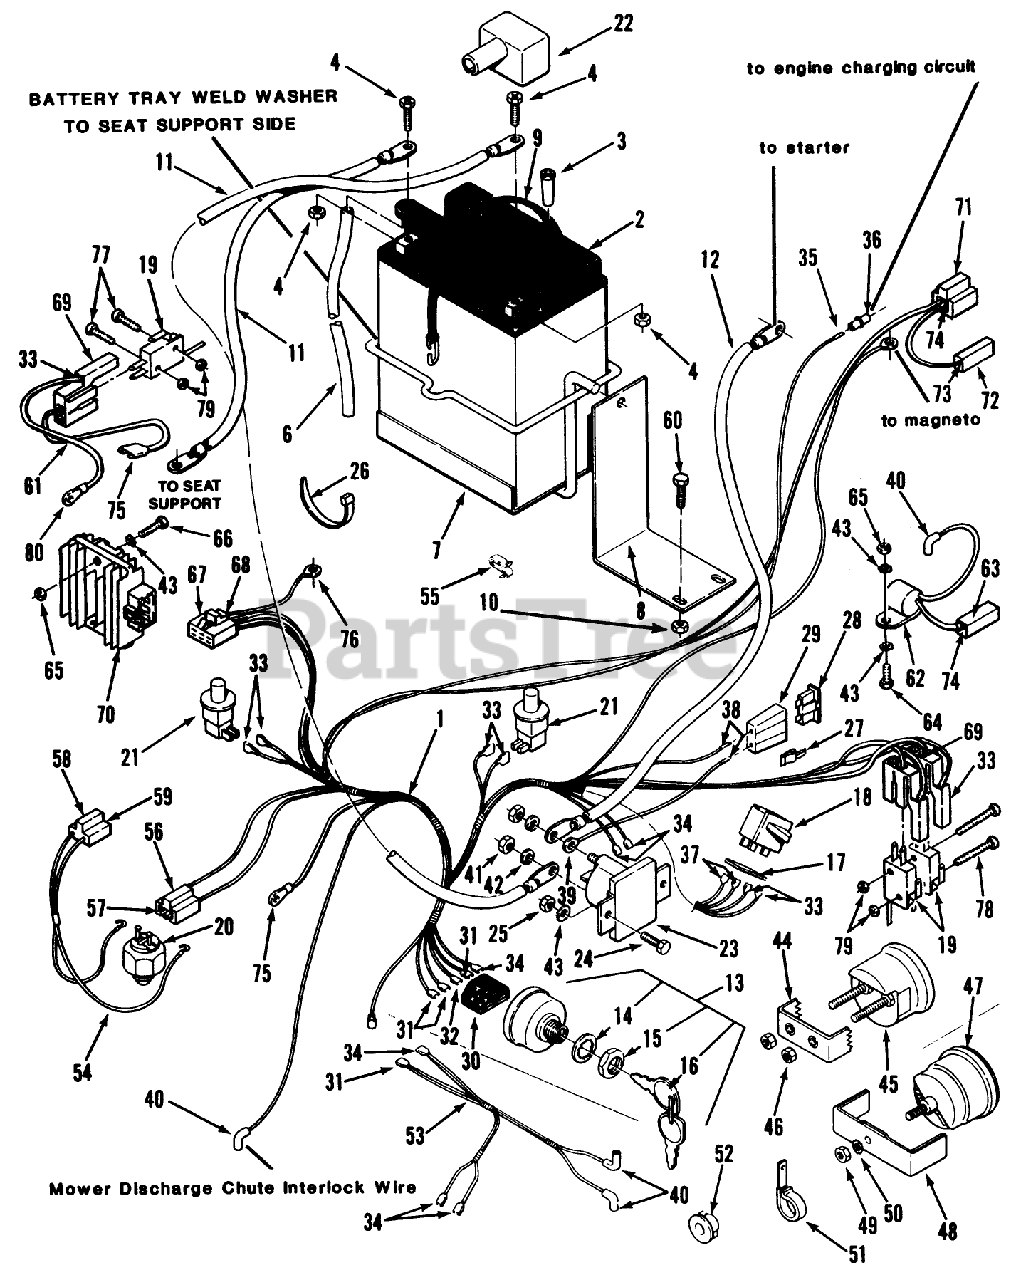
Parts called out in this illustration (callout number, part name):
7	BATTERY TRAY *B
8	BRACKET *B
12	WIRE ASM
18	SEE WH SB 442
19	SWITCH
20	SWITCH (N.C.-TRANS)
28	FUSE-BLADE, 15 AMP
33	OBTAIN LOCALLY
34	Connector .250 x .032
37	Wire Terminal (Part of 1)
44	CLAMP MOUNTING
46	HEX NUT 10-32 E.S. + + USE 3296-21 + +
51	CLAMP
54	ASSY WIRING HARNESS
56	CONNECTOR BODY
58	CONNECTOR BODY *B
59	TERMINAL-TAB RCPT
63	CONNECTOR BODY ELECT
67	6 Terminal Connector 112-C Only
68	Terminal 112-C Only
69	CONNECTOR BODY
70	Voltage Regulator 112-C Only
74	TERMINAL-LONG MALE
75	OBTAIN LOCALLY
76	Ring Terminal 1/4 (Part of 1)
78	Screw 1/4-40 x 1-1/4 112-C Only
